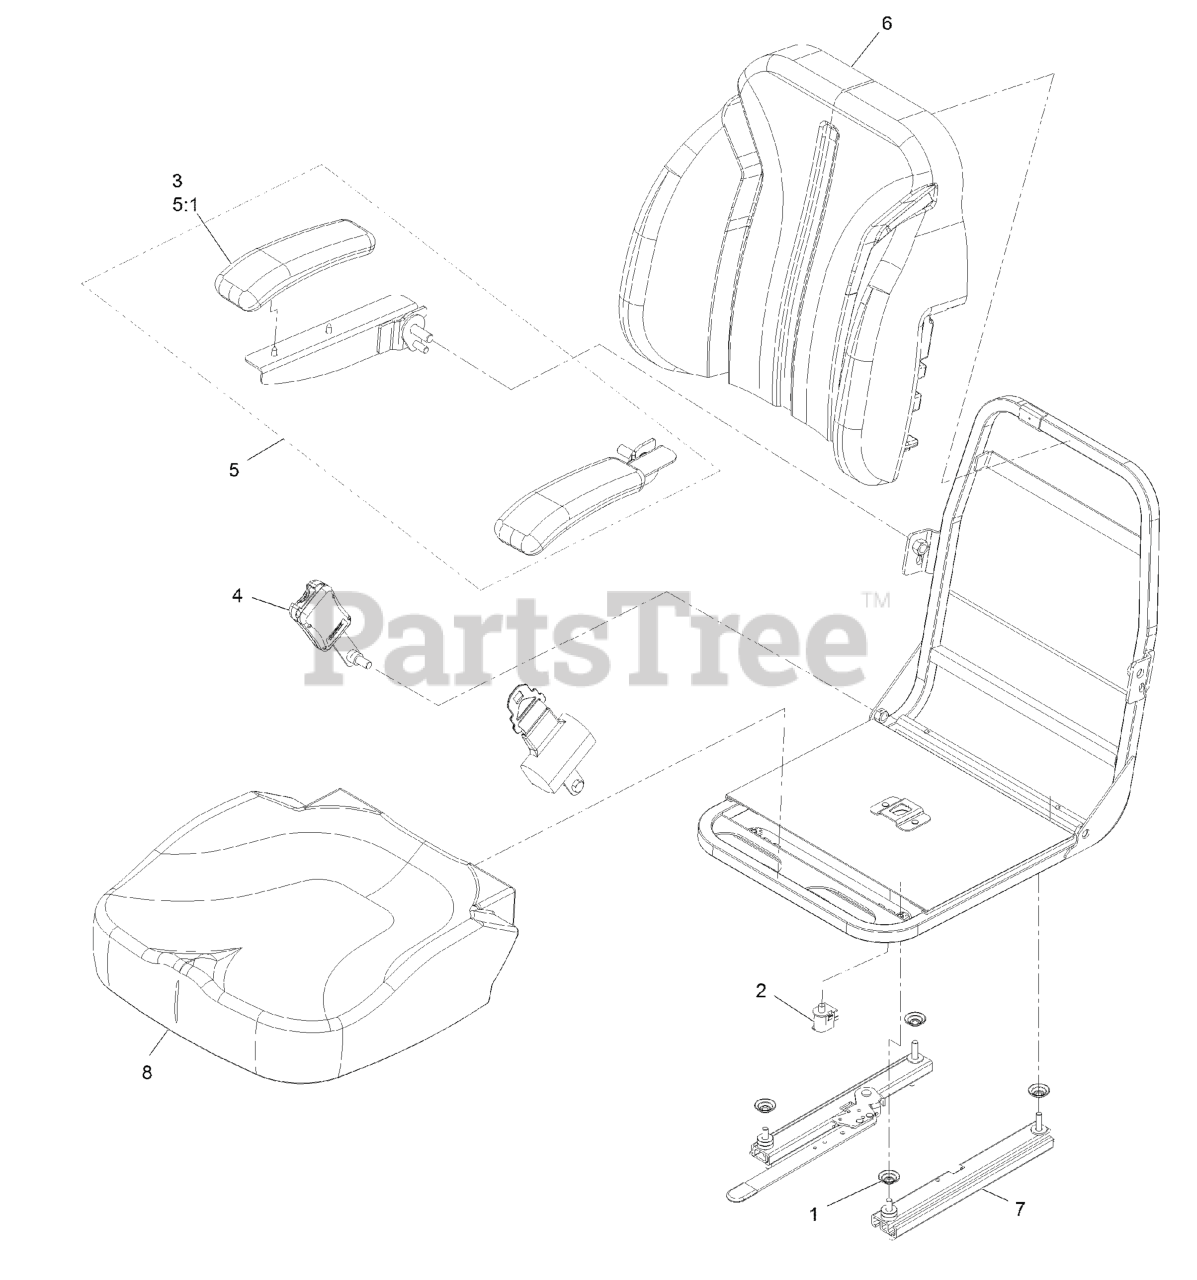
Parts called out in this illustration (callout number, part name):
1	SPACER-MOUNTING
2	SWITCH-BAIL
3	CUSHION-REST, ARM
4	SEAT BELT KIT
5	ARMREST KIT
5:1	CUSHION-REST, ARM
6	COVER-SEAT BACK SVC
7	TRACK-SEAT
8	COVER-SEAT BOTTOM SVC
